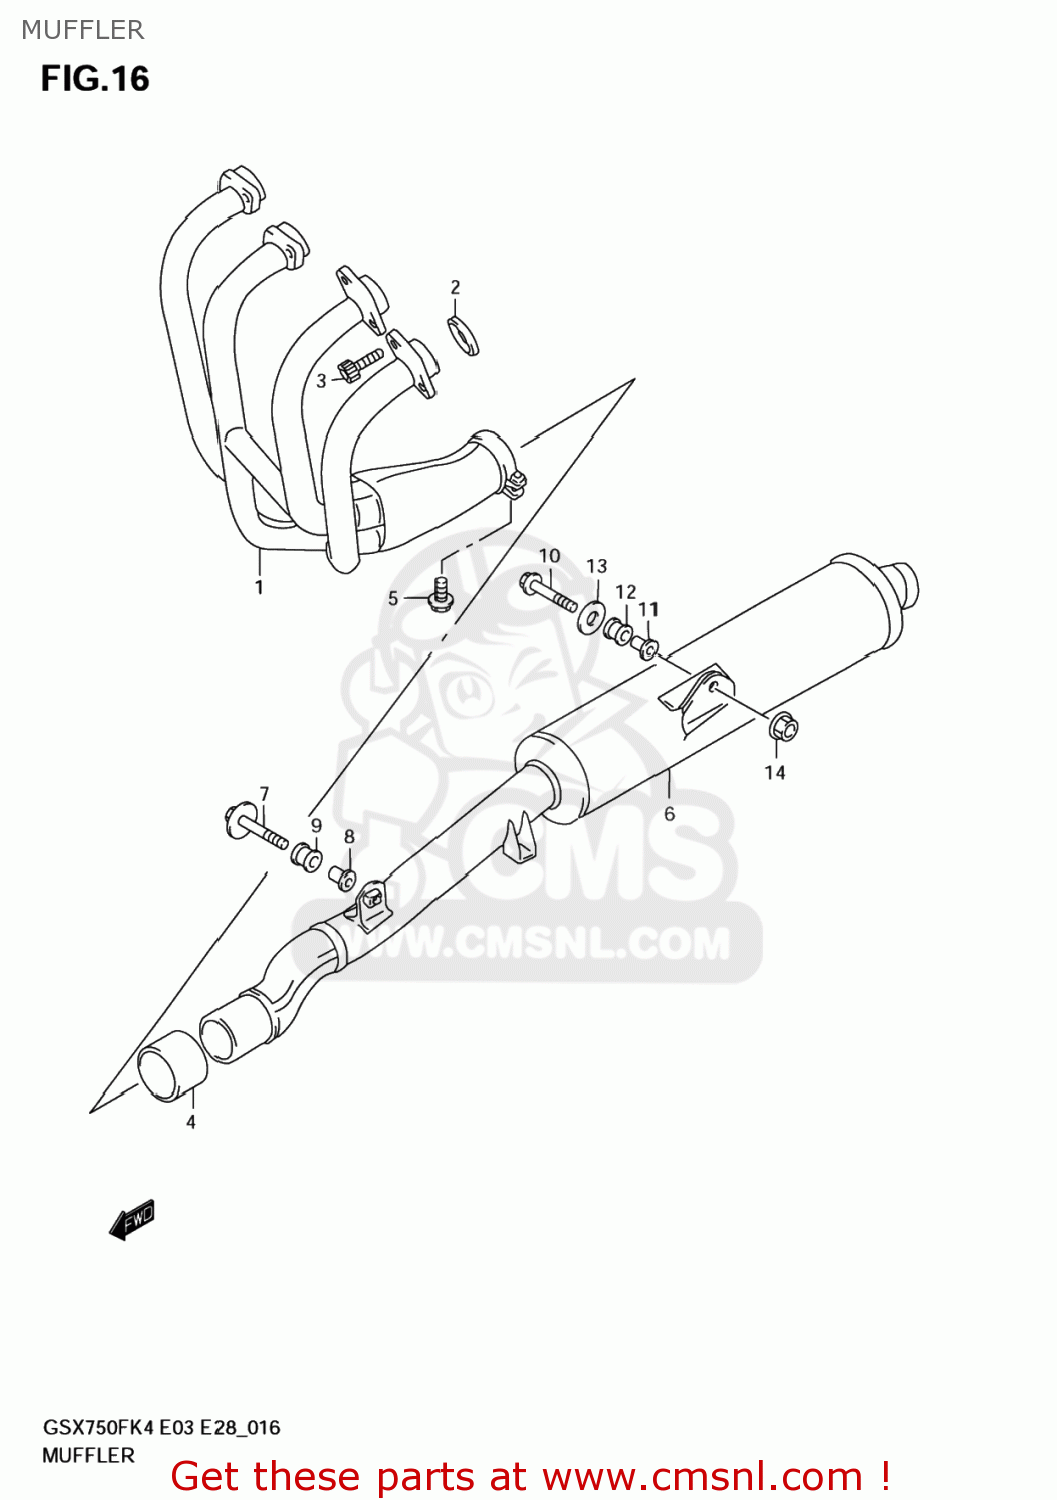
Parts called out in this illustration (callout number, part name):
1	EXHAUST
2	GASKET,EXHAUST (NAS)
3	BOLT
4	CONNECTOR,MUFFLER
5	BOLT
6	MUFFLER
7	BOLT 8X40
8	SPACER(8.6X12X24.2)
9	CUSHION
10	BOLT(8X45)
11	SPACER(8.6X12X27.1)
12	CUSHION
13	WASHER (8.5X33X1.6)
14	NUT
